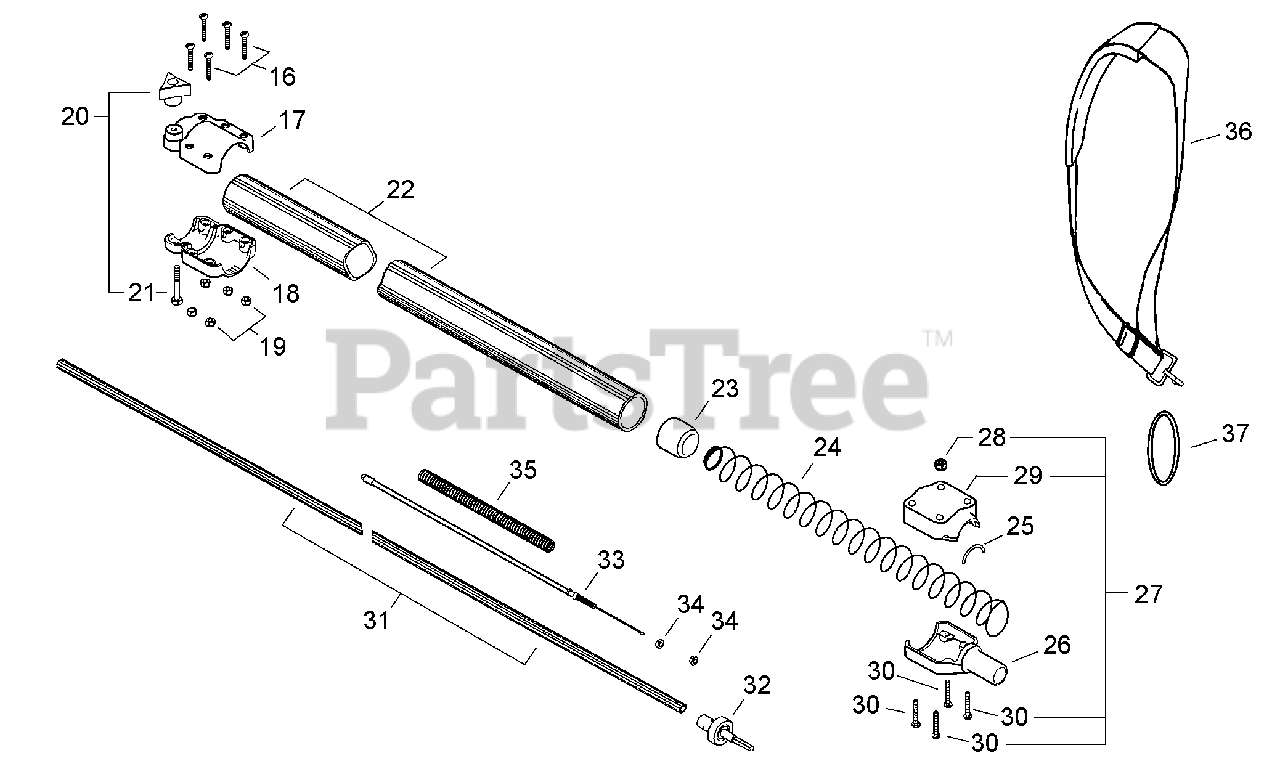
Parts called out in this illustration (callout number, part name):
16	SCREW, TORX 10-24 UNC 1-1/4
17	COLLAR, UPPER
18	COLLAR, LOWER
19	NUT, LOCK 10-24 UNC
20	THUMBSCREW
22	PIPE, MAIN 1.5 ID×60" L
23	BUSHING, FLOATING
24	SPRING, COMPRESSION
26	COUPLING, MAIN PIPE 113.6 L
27	CAP ASSY, MAIN PIPE
28	NUT, LOCK 10-24 UNC
29	CAP, MAIN PIPE
30	SCREW, TORX 10-24×1.5
31	SHAFT, LOWER DRIVE
32	CONNECTOR, DRIVE SHAFT
33	CABLE, THROTTLE
35	TUBE, FLEXIBLE
36	STRAP ASSY, SHOULDER
37	RING, HARNESS Ø32
